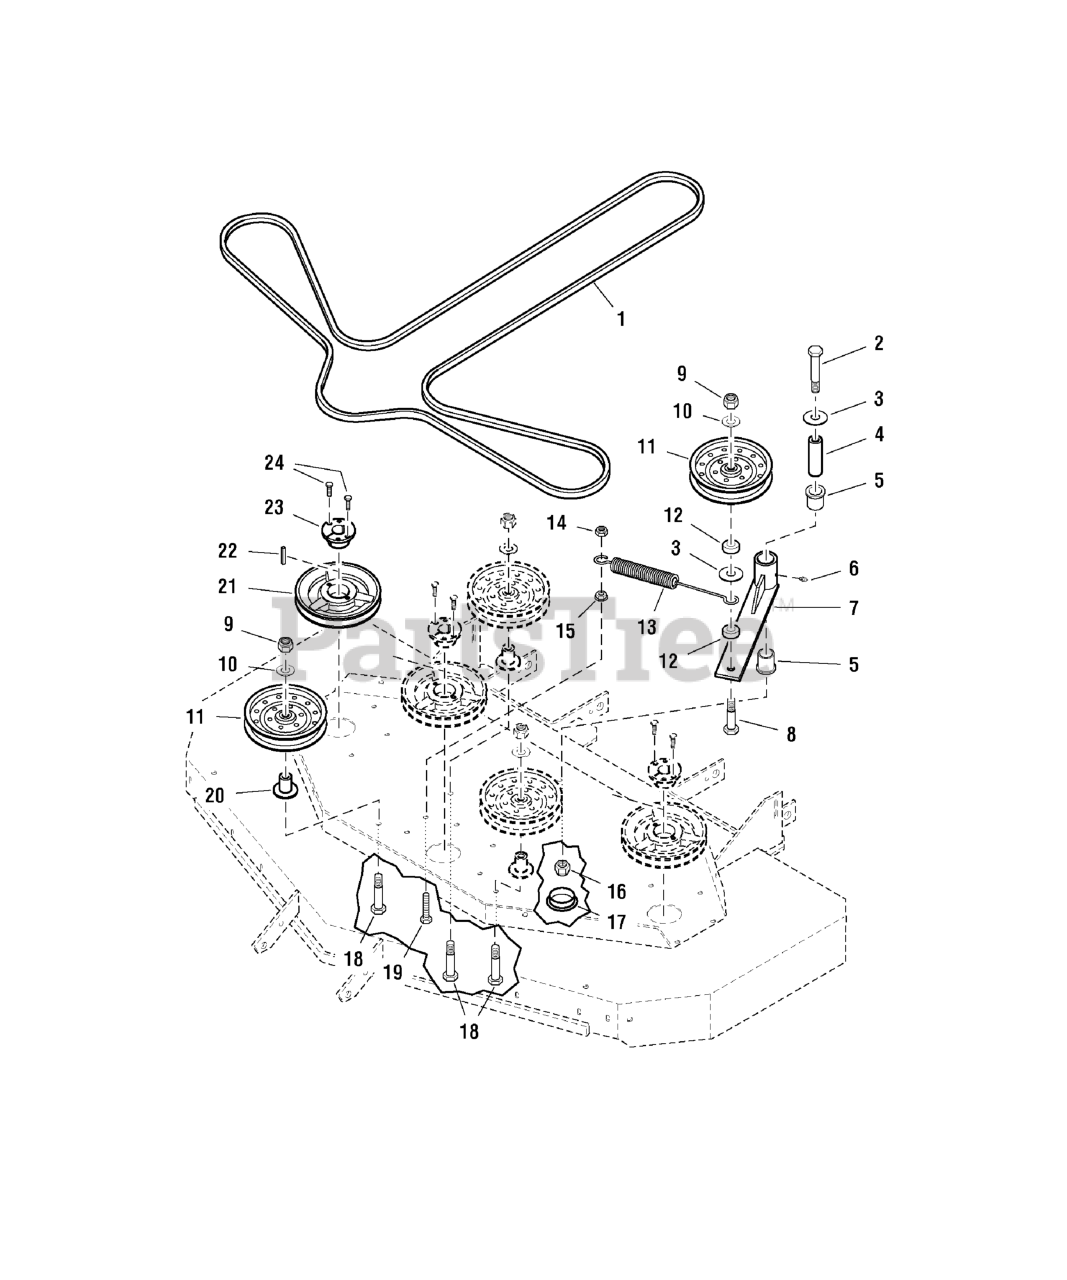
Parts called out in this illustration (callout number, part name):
1	BELT
2	BOLT, 1/2-13 X 4-1/2" GD5 YZ
3	WASHER, 1/2" USSZ
4	SPACER, .52 x 1.00 x 3.50
5	BUSHING, FLANGE
6	GREASE FITTING, 1/4-28 Straight
7	WELD, IDLER ARM - RED
8	BOLT, 1/2-20 X 3" GD5 YZ
9	NUT, Hex, Nylon Lock, 1/2-20
10	WASHER, 1/2 SAE
12	SPACER, .52 X 1.00 X .44, CZ
13	SPRING-EXT, 1.04 ODX10.535LGX.148WR, BLK
14	NUT, 3/8-16 HEX NYLON LOCK
15	NUT, 3/8-16 Hex Large Serrated Flange
16	NUT, 1/2-13 HEX NYLON LOCK
17	PLUG, HOLE 2-1/8
18	BOLT, 1/2-20 X 3-1/2" GD5 YZ
19	BOLT, 3/8-18 X 1-3/4" GD5 TFL
20	IDLER PULLEY MOUNT - RED
21	PULLEY, SPINDLE, BH66
22	KEY 1/4 SQ X 1 1/2 LONG
23	BUSHING, Tapered Hub
24	BOLT, 1/4-20 X 1" GD5 CZ
